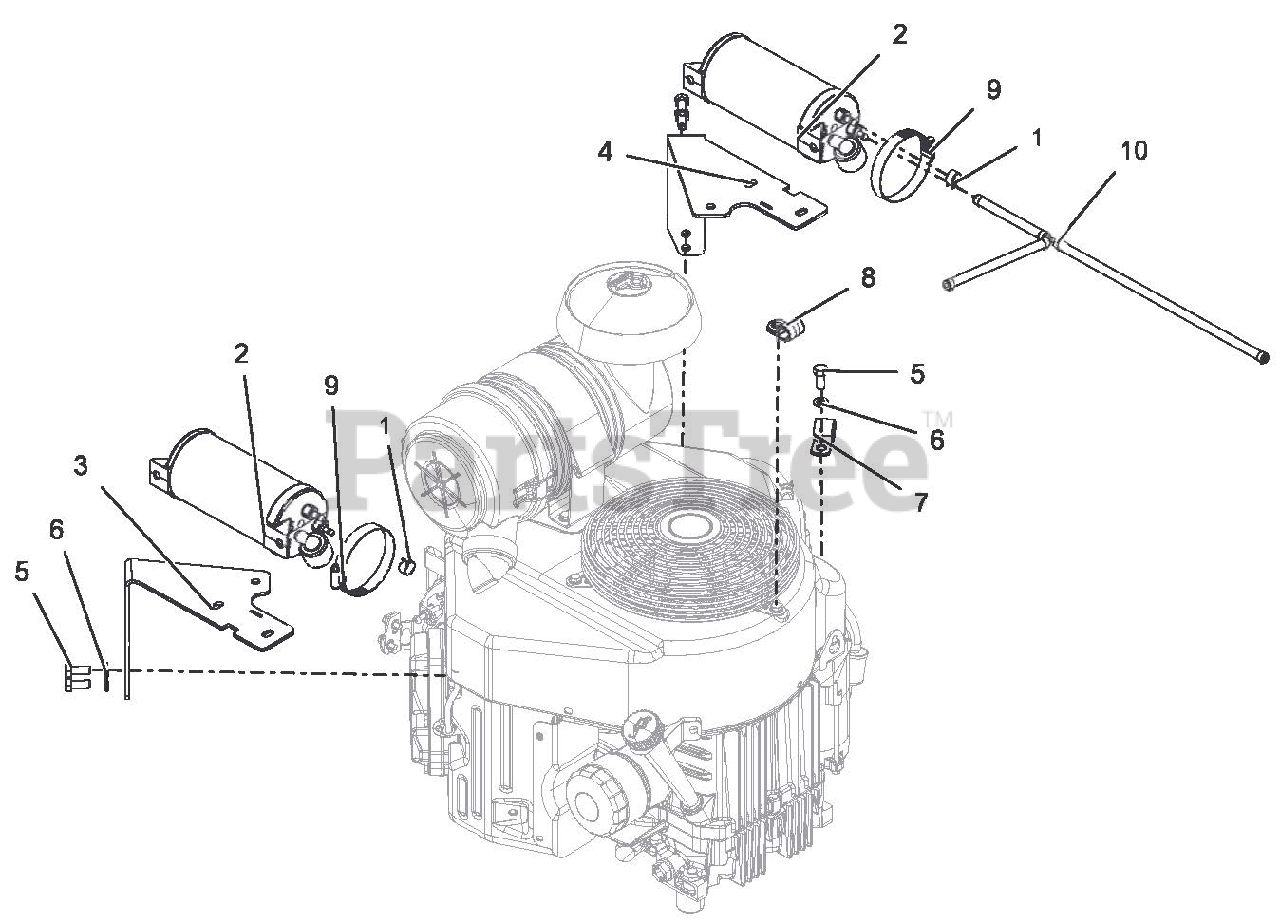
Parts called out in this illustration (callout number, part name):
1	CLAMP, FUEL LINE
2	CANISTER, CARBON 6.3 G CAP.
3	BRKT, MOUNT PT 100 RH CARB CANISTER
4	BRKT, MOUNT PT 100 LH CARB CANISTER
5	@BLT-HEX M8-1.25 X 20 YWZC
6	WSHR-LK .31X.078 REG YWZC
7	CLAMP, CUSHIONED STEEL .75
8	CLAMP, CUSHIONED STEEL
9	CLAMP, HOSE 2.3/3.2
10	ASM, FUEL LINE, PT100
